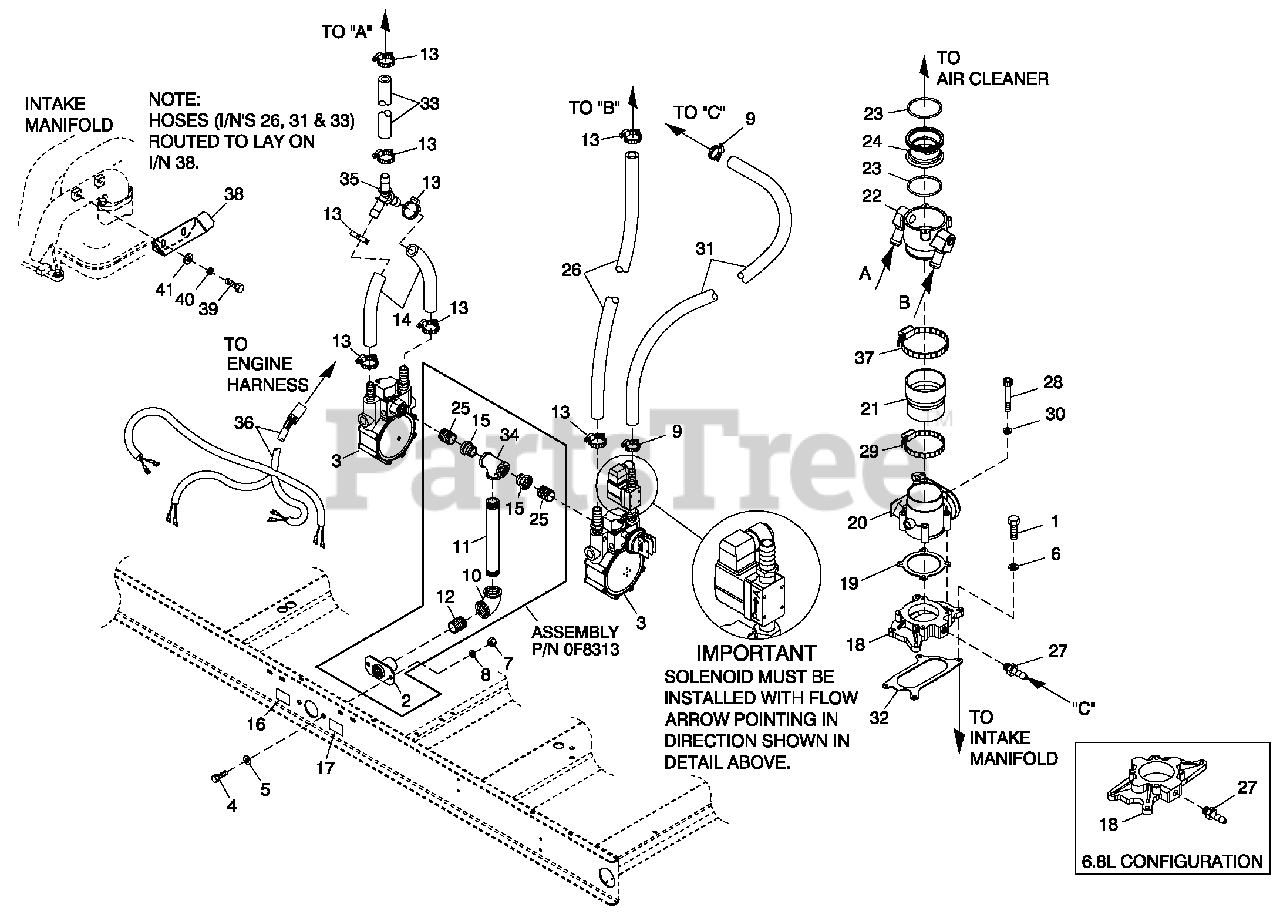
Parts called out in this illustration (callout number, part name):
1	SCREW HHC M6-1.0 X 35 G8.8 BLK
2	SUPPORT NAT GAS SOLENOID
3	REGULATOR ASSM 5.4L 80KW NG
4	SCREW HHC M12-1.75 X 20 G8.8
5	WASHER FLAT 1/2 ZINC
6	WASHER LOCK M8-5/16
7	NUT HEX M12-1.75 G8 YEL CHR
8	WASHER LOCK 1/2
9	CLAMP HOSE #5.5 .62-.62 (5.4L)
10	ELBOW 90D 1-1/4 NPT
11	NIPPLE PIPE 1-1/4 NPT X 3
12	NIPPLE CLOSE 1.25 NPT X 1.625
13	CLAMP HOSE #8 .53-1.00
14	HOSE 3/4 ID SAE-30R2 (42" LG)
15	BSHG RDCR HEX 1-1/4-3/4
16	DECAL INLET PRESSURE
17	DECAL FUEL INLET NG
18	MACHINING INTAKE ADAPTOR 60MM (5.4L FORD)
19	GASKET GOVERNOR ACTUATOR
20	ACTUATOR BOSCH 60 GOVERNOR
21	REDUCER 3.0" TO 2.75" TURBO
22	MIXER 40/60MM ACTUATOR ASSY
23	O-RING 2-3/4 X 3/32 X 2-15/16
24	VENTURI THROTTLE 38MM (5.4L 80KW)
25	NIPPLE CLOSE 3/4 X 1.375
26	HOSE 3/4 ID SAE-30R2 (42" LG)
27	BARBED STR 1/4 NPT X 3/8 (5.4L 80KW & 100KW NG)
28	SCREW SHC M6-1.0 X 45 G12.9
29	CLAMP HOSE #44 2.31-3.25
30	WASHER LOCK M6-1/4
31	HOSE 3/8 ID SINGLE BRAID (42" LG)
32	GASKET ADAPTER THROT BODY (6.8L FORD ONLY)
33	HOSE 3/4 ID SAE-30R2 (42" LG)
34	PIPE TEE 1-1/4 NPT
35	Y CONNECTOR 500 SERIES BARBS
36	HARNESS FUEL JUMPER DUAL REG
37	CLAMP HOSE #52 2.81-3.75
38	BRACKET, HOSE RISER
39	SCREW HHC M6-1.0 X 20 G8.8
40	WASHER LOCK M6-1/4
41	WASHER FLAT M6
